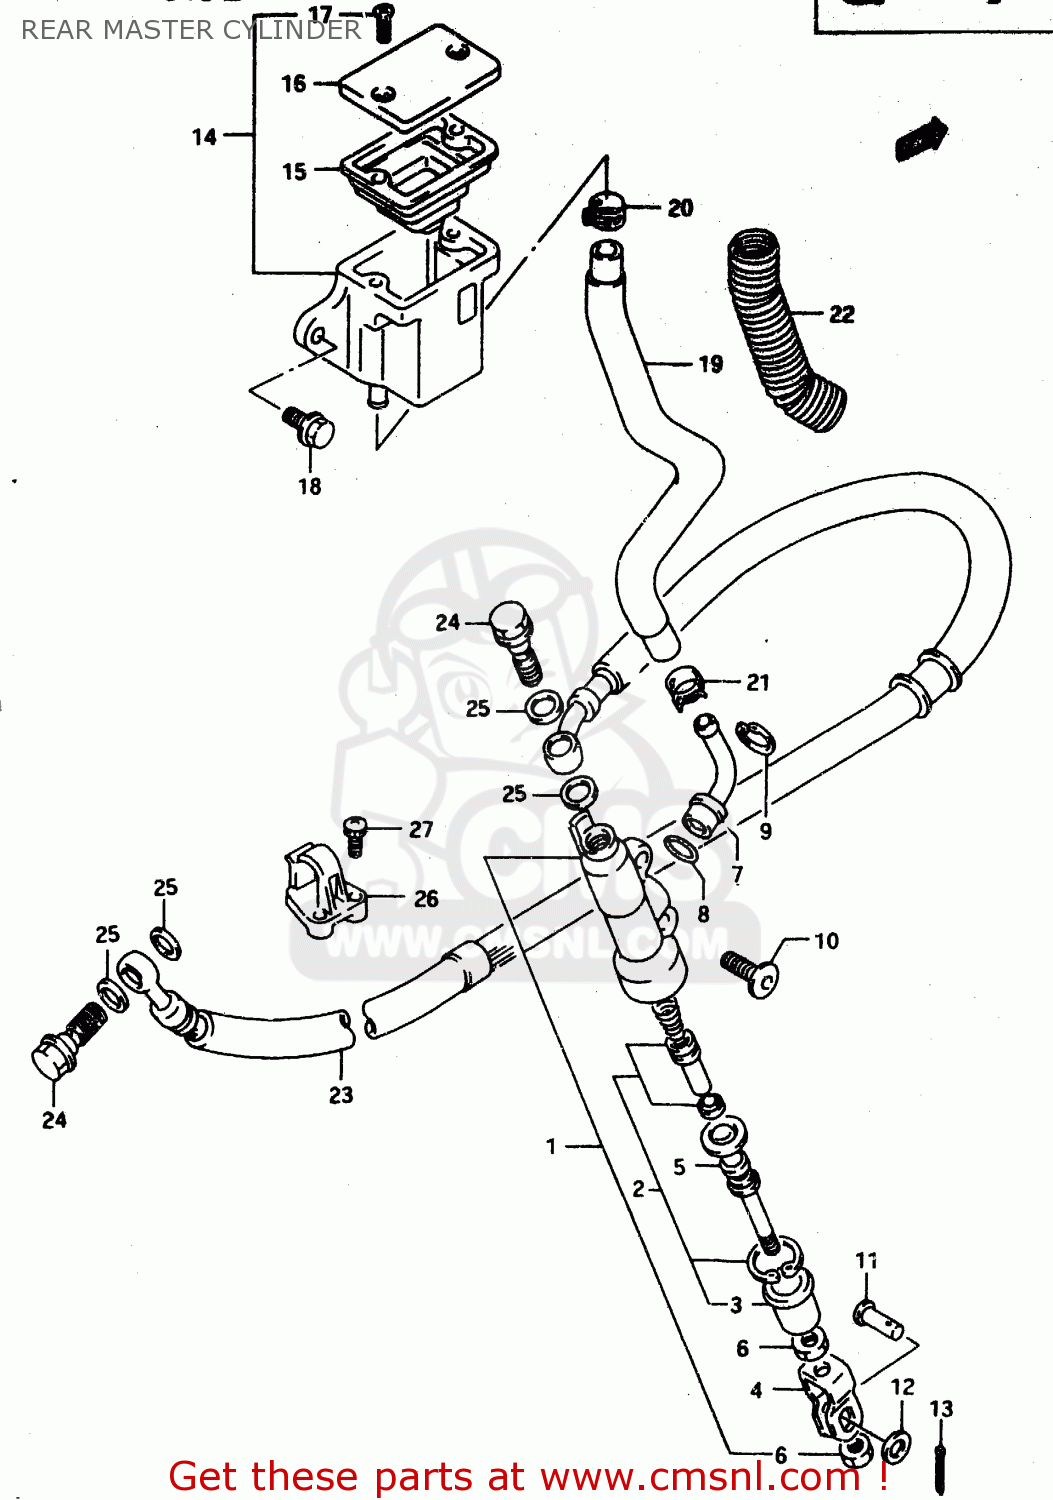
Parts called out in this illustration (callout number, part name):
1	CYLINDER ASSY,RR MASTER
2	PISTON/CUP SET
3	BOOT
4	YOKE
5	ROD,PUSH
6	NUT
7	CONNECTOR
8	O RING
9	CIRCLIP
10	BOLT(6X18)
11	PIN
12	WASHER
13	PIN
14	TANK ASSY,RESERVOIR
15	DIAPHRAGM
16	CAP
17	SCREW
18	BOLT
19	HOSE COMP,RESERVOIR TANK
20	CLIP
21	CLIP
22	SHIELD,RSVR TANK HOSE HEAT RR
23	HOSE COMP,REAR BRAKE
24	BOLT UNION
25	WASHER(10X15X1.5)
26	GUIDE,RR BRAKE HOSE
27	SCREW
